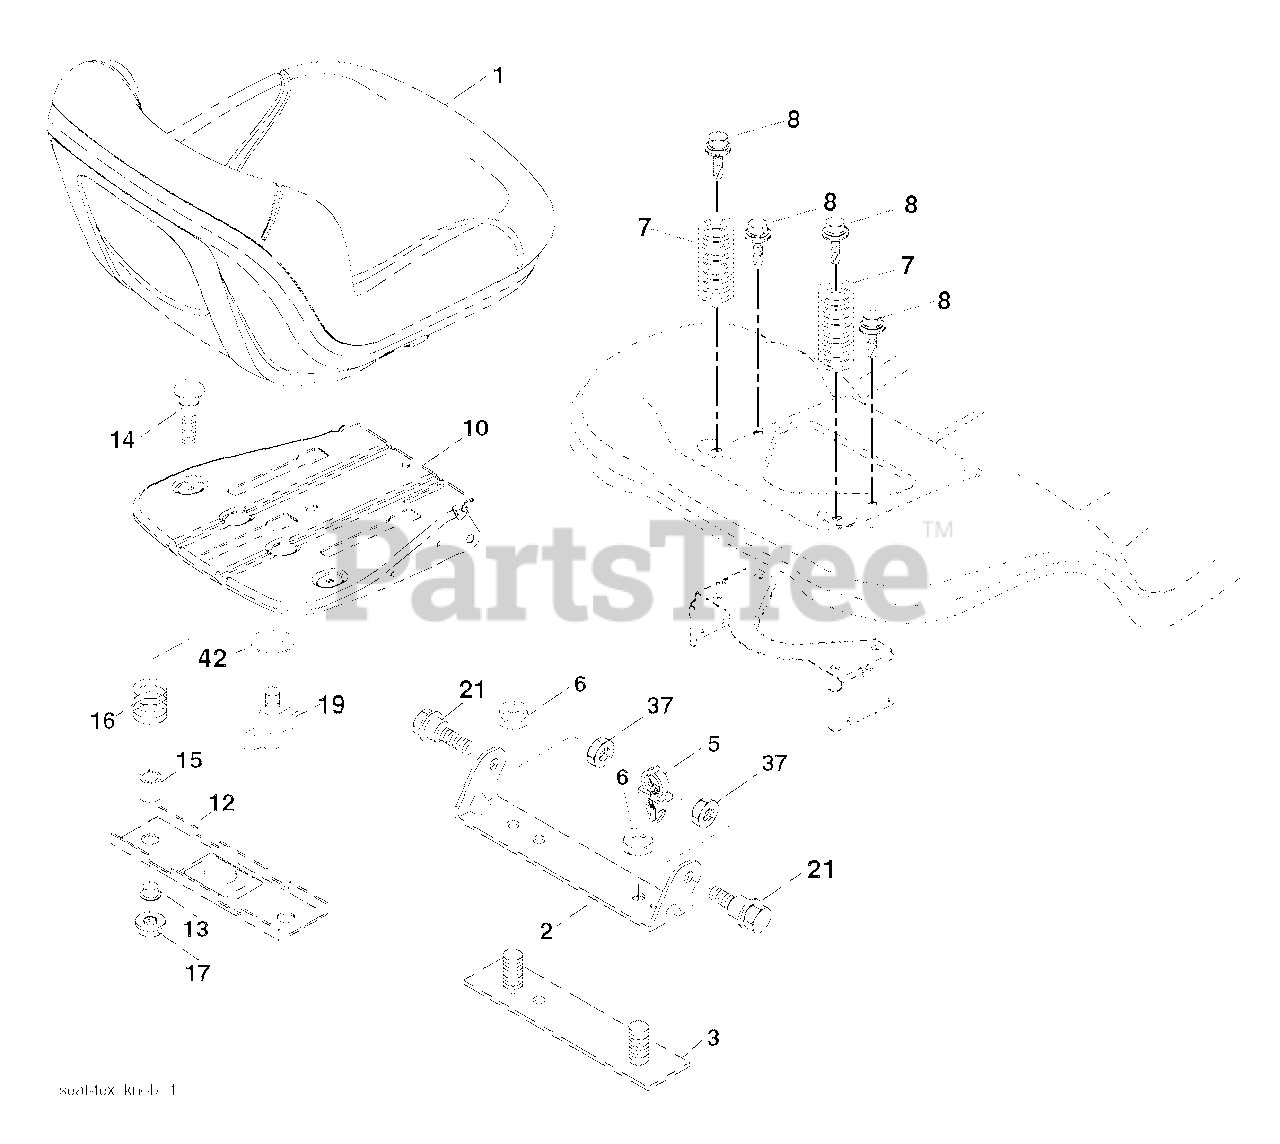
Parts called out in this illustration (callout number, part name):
2	BRKT.PIVOT.FENDER
5	PUSH CLIP
6	NUT
7	SPRING COMPRESSION
8	BOLT, 5/16-18 X 1 3/4
10	PAN.ASM.SEAT.SHORT.SLD.ADJ.TEX
12	KNOB.SEAT.ADJ.
14	BOLT.ROUND.HEAD.SQUARE.NECK
15	SPACER SPLIT 28X.96
16	SPRING COMPRESSED
17	NUT T
19	KNOB.SEAT.ADJ.
21	BOLT.SHOULDER.5/16-18
37	NUT.71038.31-18.HEX.NYLOCK
42	WASHER.CUP.SEAT.
